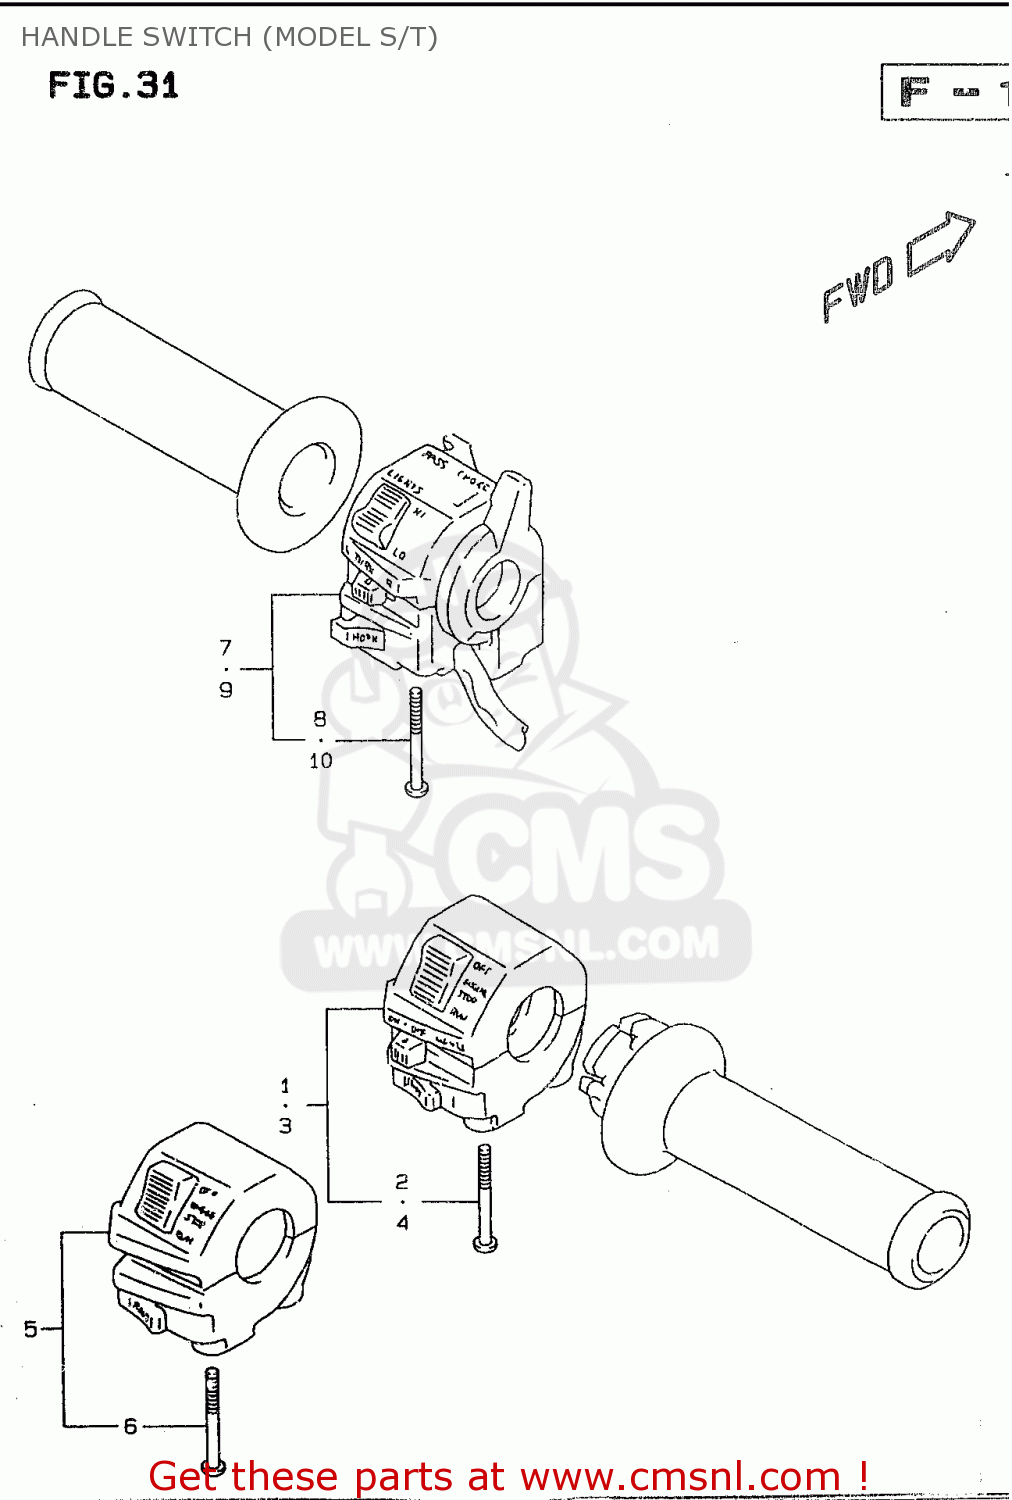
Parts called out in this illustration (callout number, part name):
1	SWITCH ASSY,RH
2	SCREW, 5X45
3	SWITCH ASSY, HANDLE, RH
4	SCREW, 5X45
5	SWITCH ASSEMBLY,RIGHT
6	SCREW, 5X45
7	SWITCH ASSY,HANDLE,L
8	SCREW, 5X45
9	SWITCH,HANDLE,
10	SCREW, 5X45
